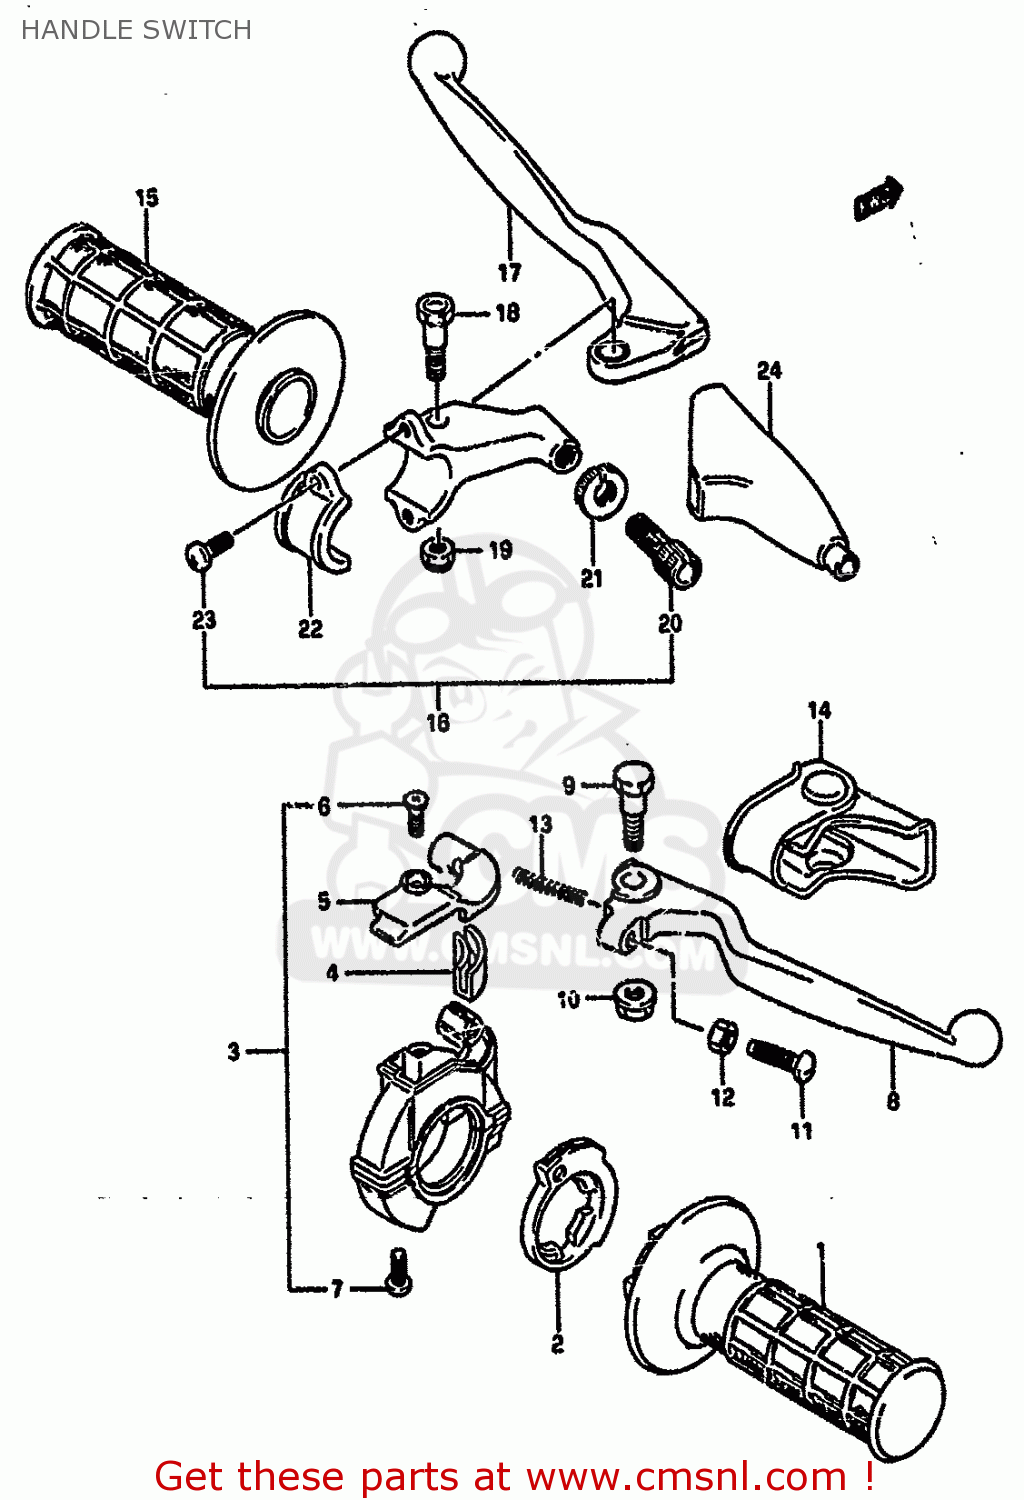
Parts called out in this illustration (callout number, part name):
1	GRIP,THROTTLE
2	ROTOR,THROTTLE GRIP
3	CASE ASSY,THROTTLE
4	GUIDE PIECE,THROTTLE
5	COVER,THROTTLE CASE
6	SCREW 4X10
7	SCREW
8	LEVER,BRAKE
9	BOLT,BRAKE LEVER
10	NUT,BRAKE LEVER
11	BOLT,ADJUST
12	NUT ,5MM
13	SPRING,RETURN
14	COVER,BRAKE LEVER
15	GRIP,L
16	LEVER ASSY,CLUTCH
17	LEVER,CLUTCH
18	BOLT,LEVER
19	NUT 6MM
20	ADJUSTER,CABLE
21	NUT,CABLE ADJUSTER
22	BRACKET,CLUTCH LEVER HOLDER
23	SCREW(5X14)
24	COVER,CLUTCH LEVER
